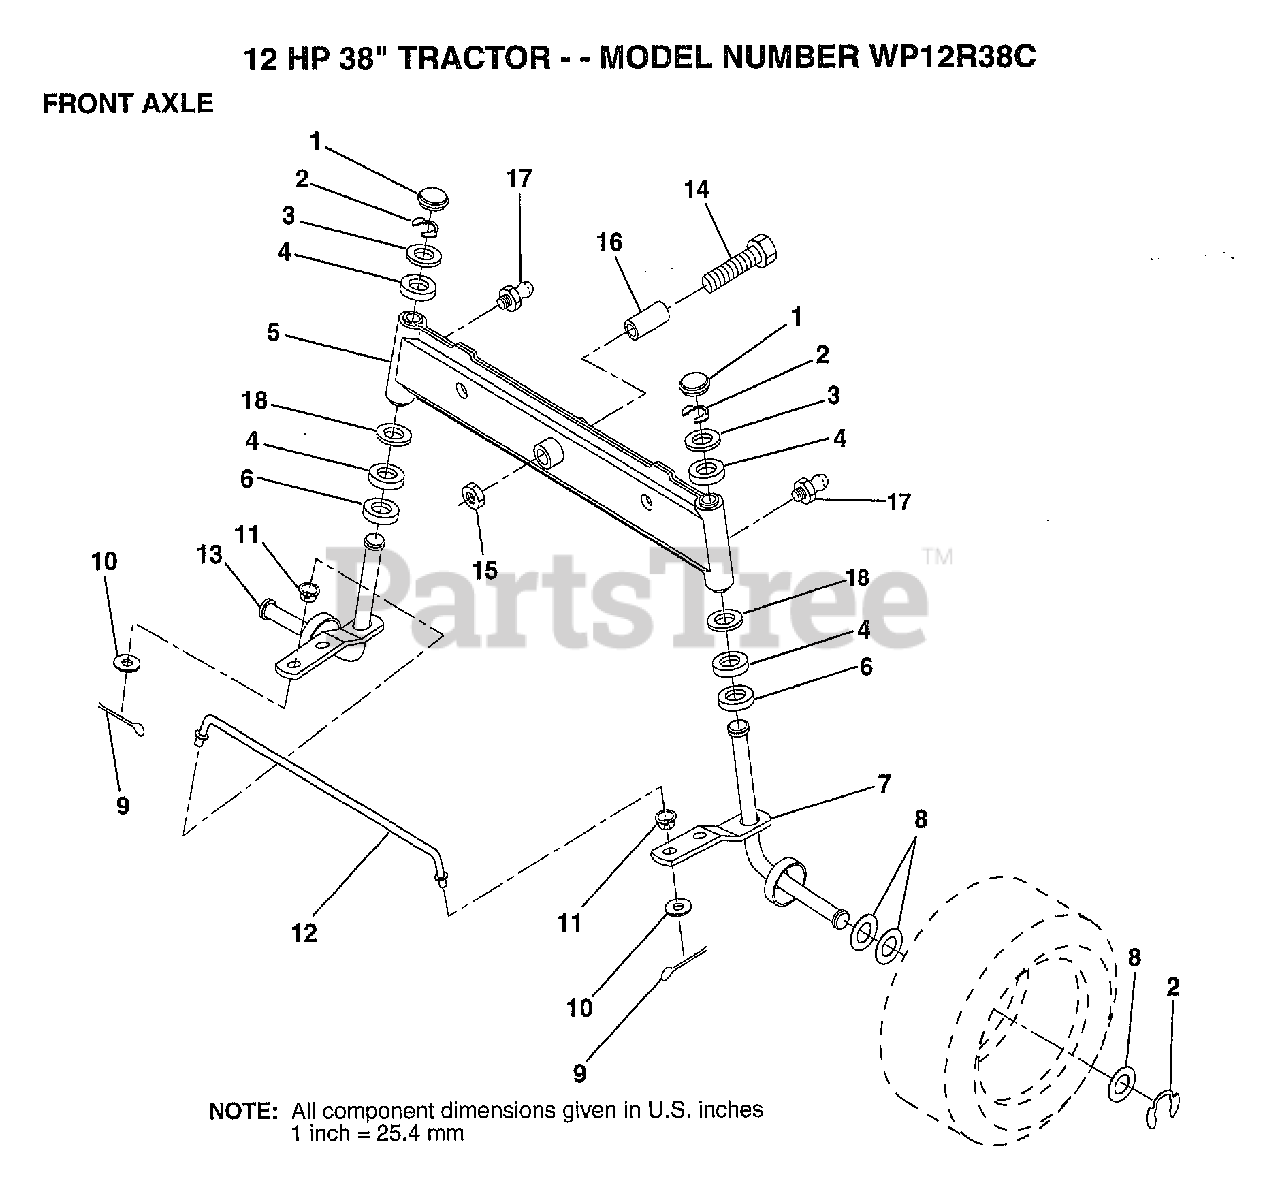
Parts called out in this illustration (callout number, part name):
1	CAP
2	RING
3	WASHER
4	COL. SRTG. BEAR.
5	AXLE ASM FRONT
6	WASHER .T
7	SPINDLE ASM RH
8	WASHER
9	COTTER PIN
10	WASHER
11	BUSHING.DRAGLINK
12	TIE ROD
13	SPINDLE ASM LH
14	BOLT HEX 5/8-11
15	"NUT-LOC,FLANGE LT"
16	BEARING
17	ZERK M
18	WASHER
